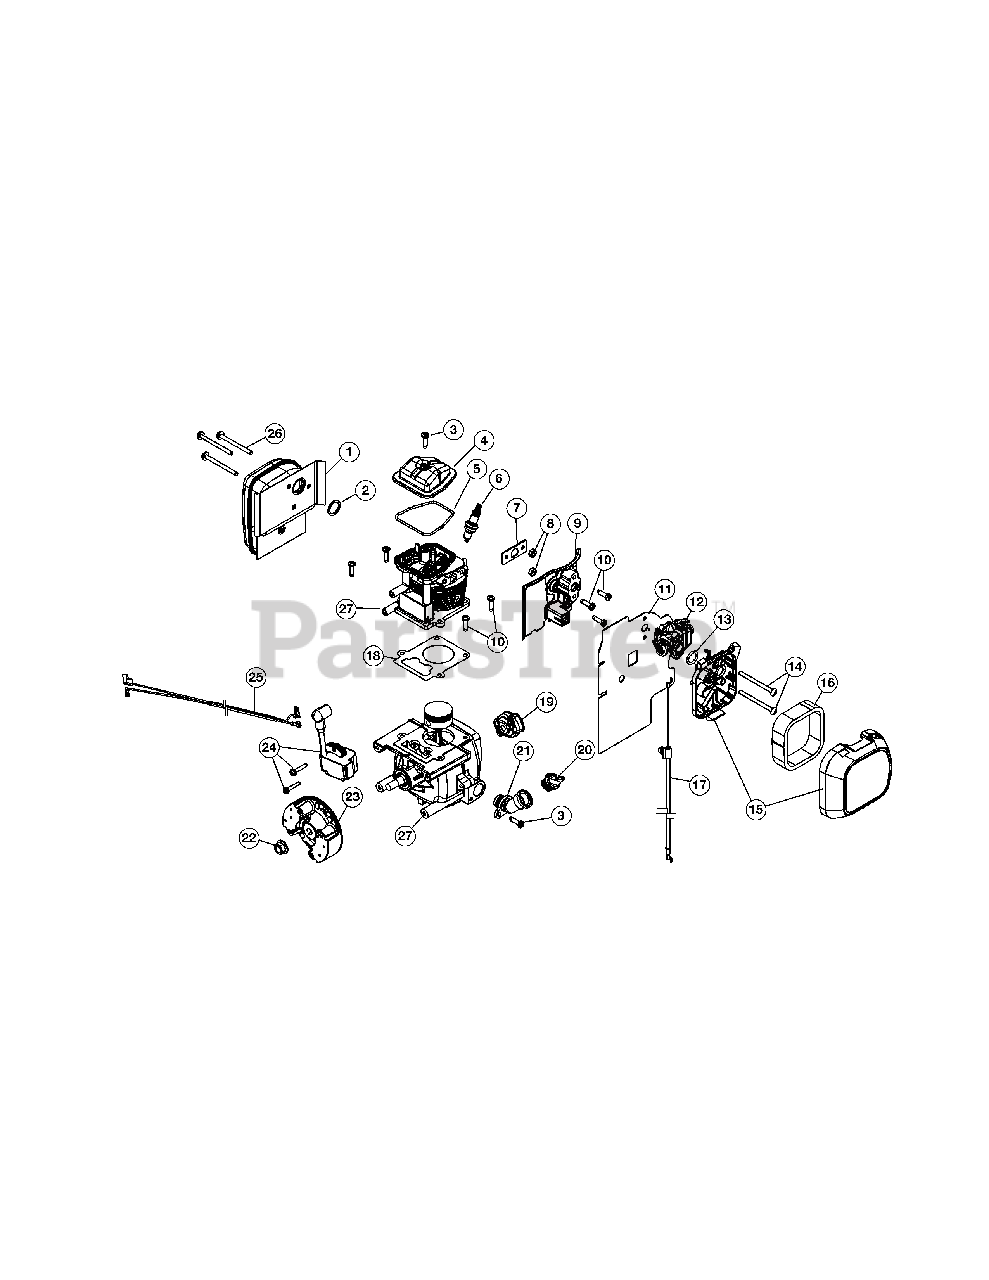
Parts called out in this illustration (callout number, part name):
1	Muffler Assembly (includes 2 & 26)
2	Muffler Gasket
4	Rocker Cover
5	Rocker Cover O-Ring
6	Spark Plug
7	Insulator Gasket
10	Screw
11	Carburetor Gasket
12	Carburetor
13	Carburetor O-Ring
15	Air Cleaner Assembly (includes 16)
16	Air Filter
17	Throttle Cable
18	Cylinder Gasket
19	Pawl Assembly
20	Oil Plug
21	Oil Fill Tube (includes 3)
23	Flywheel Asssembly
24	Module Assembly
26	Muffler Screw
27	Short Block Assembly
